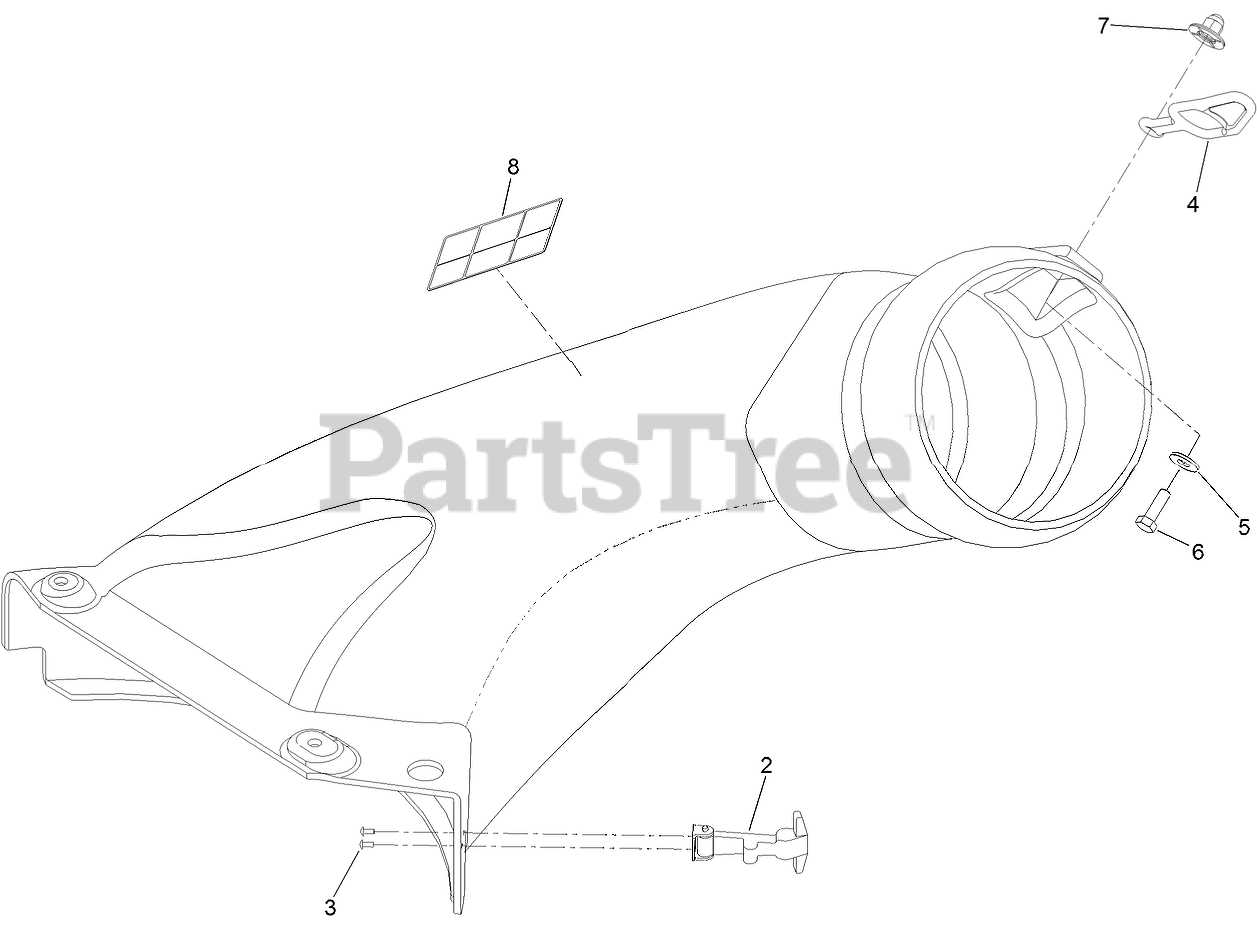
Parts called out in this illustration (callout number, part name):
2	HANDLE ASM
3	RIVET-POP
4	RETAINER-DUCT
5	WASHER-FLAT
6	SCREW-HH
7	NUT-IMPELLER
8	DECAL-DANGER
